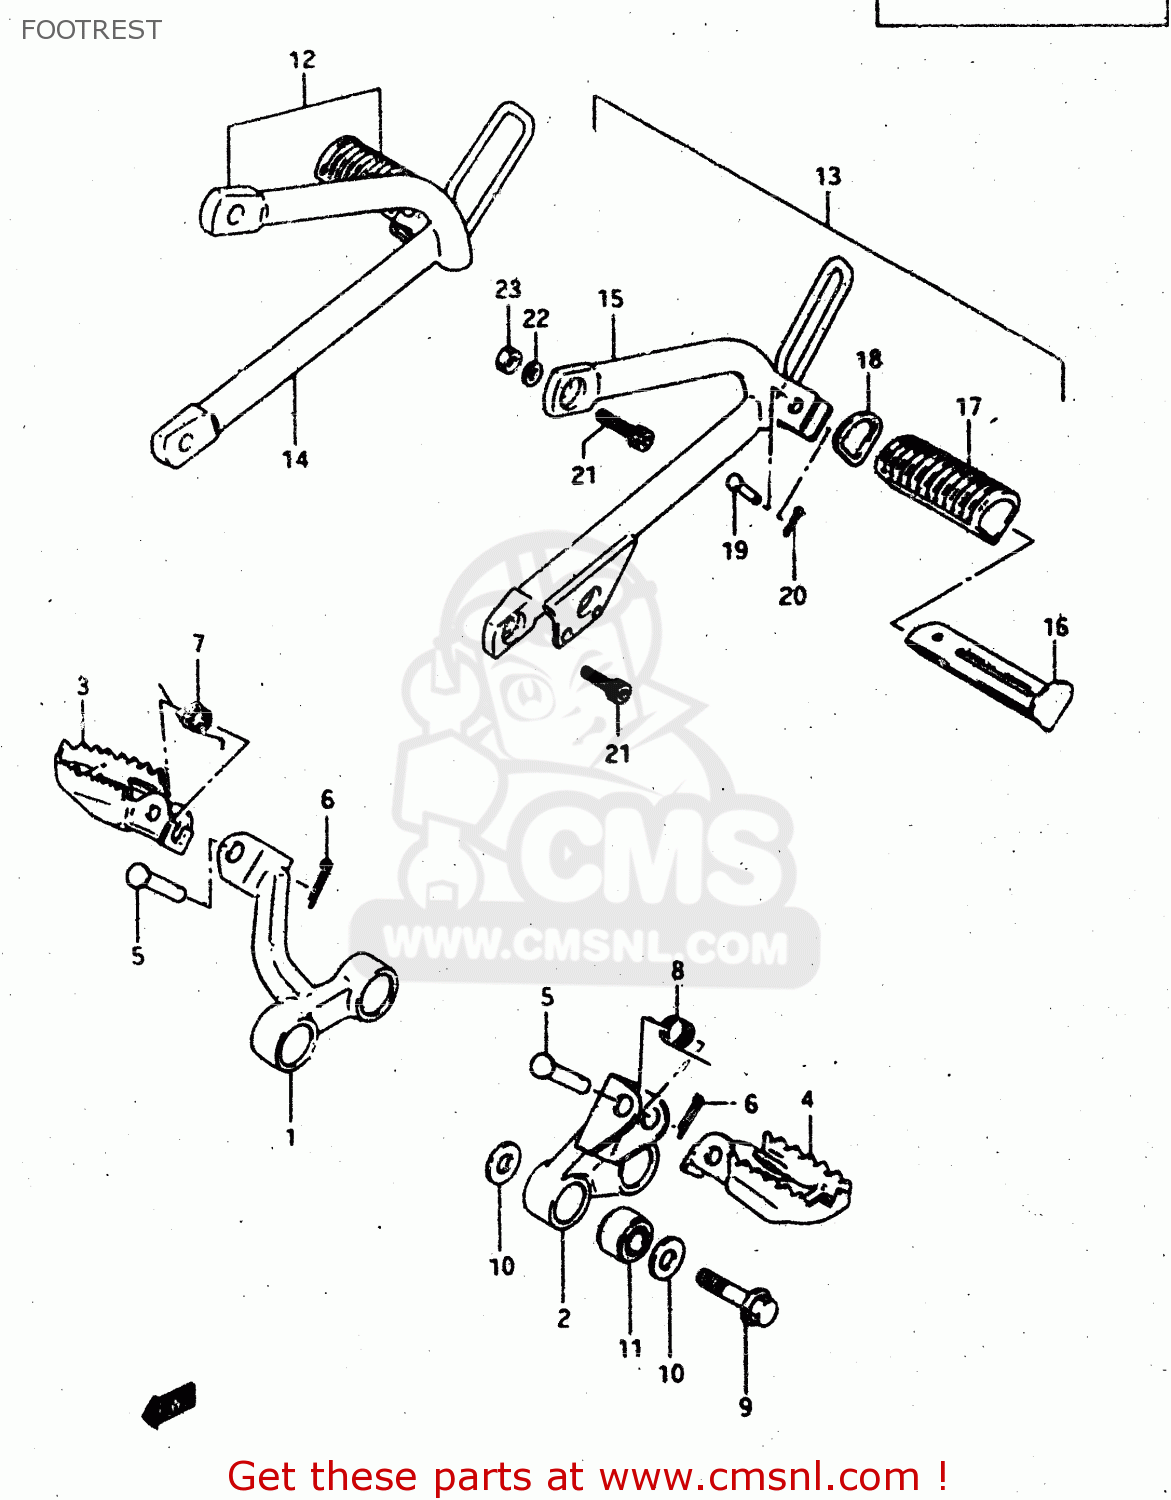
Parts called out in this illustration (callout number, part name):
1	BAR, FOOTREST RH (BLUE)
2	BAR, FOOTREST LH (BLUE)
3	FOOTREST, FRONT RH (BLUE)
4	FOOTREST, FRONT LH (BLUE)
5	PIN
6	PIN 20X20
7	SPRING
8	SPRING
9	BOLT(10X50)
10	WASHER
11	BUSH(10.2X25X19)
12	FOOTREST, PILLION RH (BLUE)
13	FOOTREST, PILLION LH (BLUE)
14	HOLDER, RH (BLUE)
15	HOLDER, LH (BLUE)
16	BAR COMP,PILLION FOOTREST
17	RUBBER,PILLION FOOTREST
18	WASHER,PILLION FOOTREST
19	PIN
20	PIN
21	BOLT
22	WASHER,LOCK,8.
23	NUT
